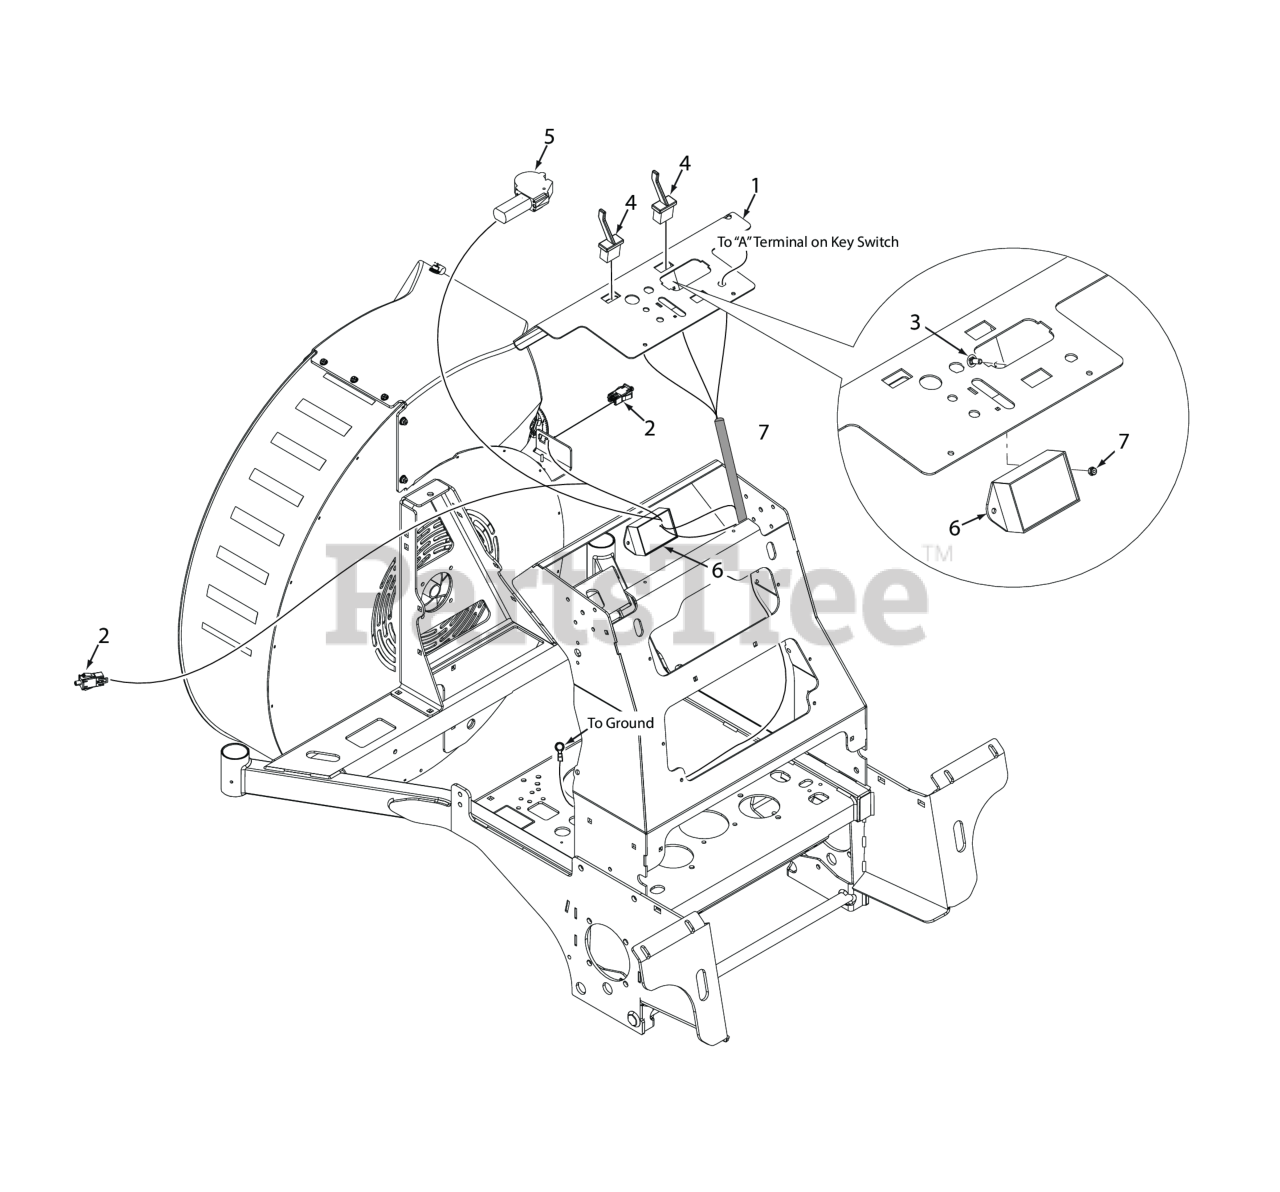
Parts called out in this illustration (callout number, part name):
1	Control Panel w/Decals
2	Switch, Plunger, Double Pole, Snap
3	Bolt, Carriage #10-24 x 1/2"
4	Switch, Nozzle Direction
5	Motor, Gear Drive
6	Module, Nozzle Control
7	Nut, Elastic Stop #10-24
